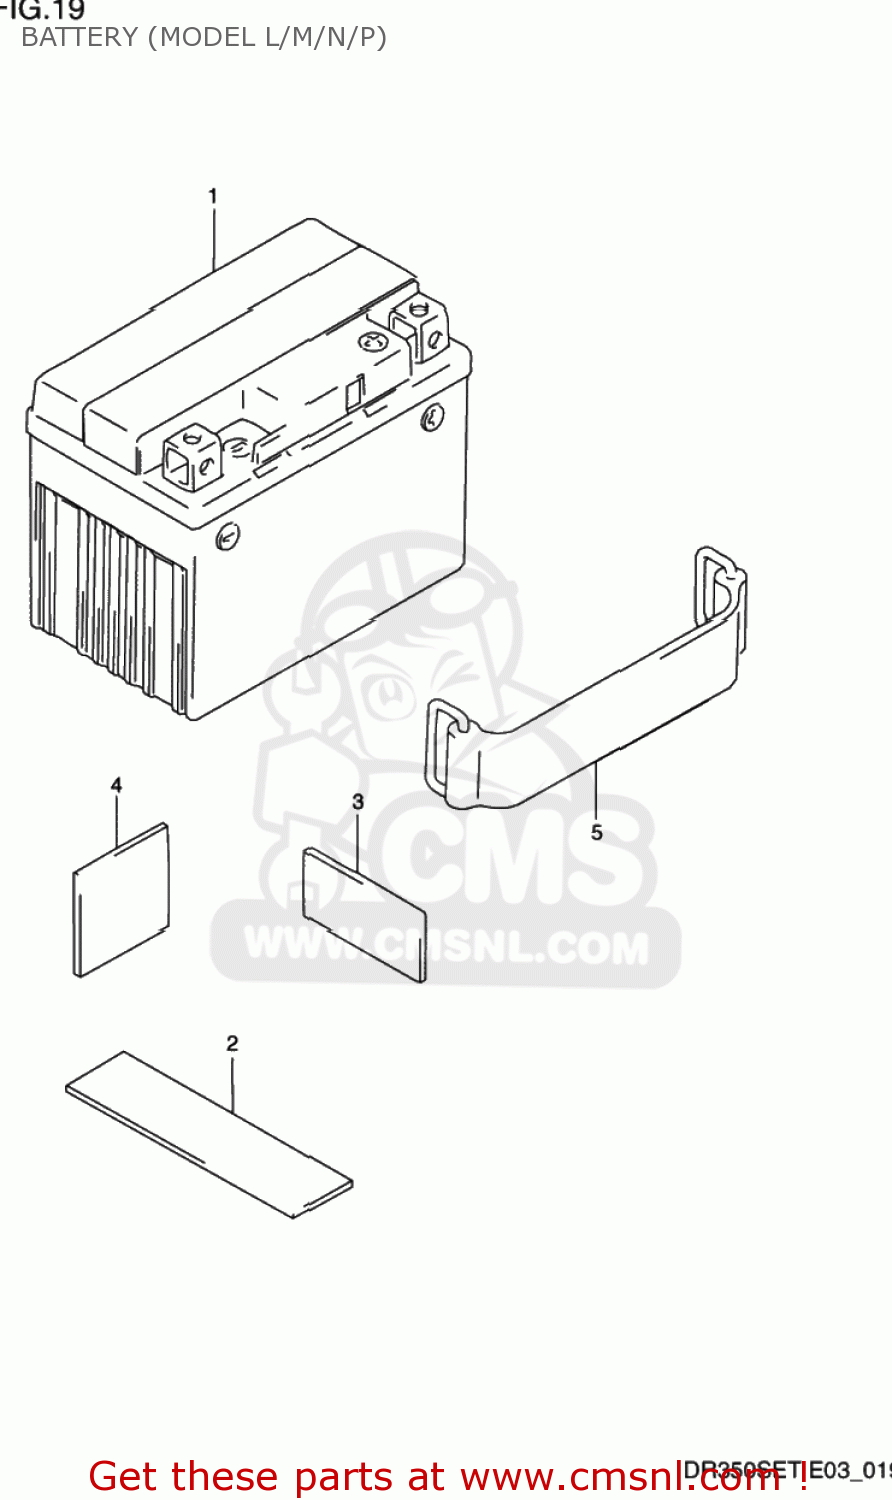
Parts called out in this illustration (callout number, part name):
1	BATTERY ASSEMBLY
2	PROTECTOR,BATTERY
3	PROTECTOR,BATTERY
4	PROTECTOR,BATTERY
5	BAND
